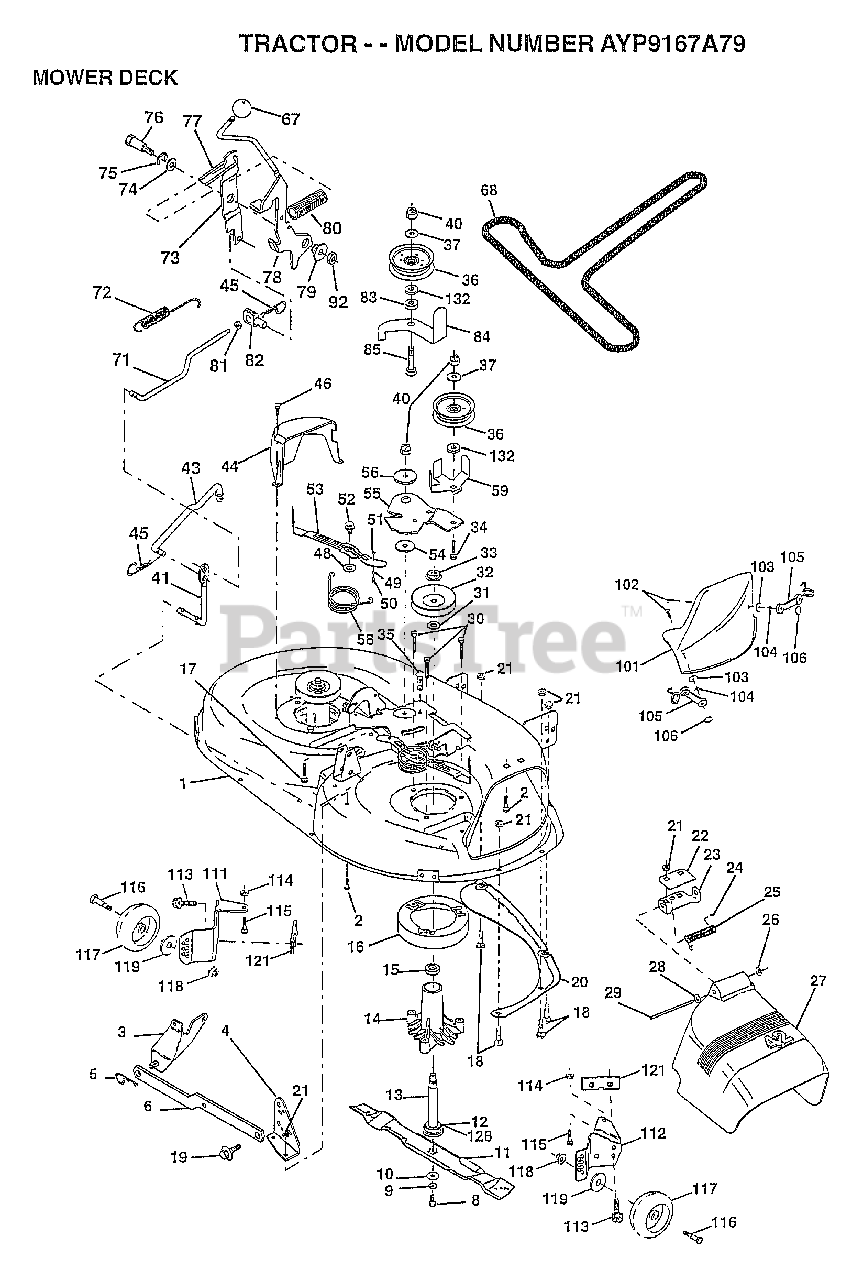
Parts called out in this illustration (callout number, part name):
1	DECK.WELD.42.
2	BOLT
3	BRKT ASM SWAY BAR
4	BRKT DECK SW BAR
8	BLADE BOLT
10	WASHER.HARD.BLADE
11	"BLADE.42"" MULCHER"
12	BEARING.BALL
14	HSG ASM MANDREL
15	BEARING
16	STRIPPER RND MWR
17	BOLT RDHD 3/8-16
18	BOLT
19	BOLT SHD 5/16-18
22	STIFFENER BRKT
23	DEFLECTOR BRKT
24	CAP-SLEEVE LT
25	SPRING TORSION
26	NUT PUSH M
27	DEFLECTOR.SHIELD
28	WASHER
29	HINGE ROD
31	WASHER
32	PULLEY.MANDREL.42
34	BOLT
35	XMAS TREE FASTNER
36	FLAT IDLER PULLEY
37	WASHER
41	PIVOT ROD
43	ROD CLUTCH W/NIBS
44	GUARD MAND LH BLK
45	RETAINER M
46	SCREW.1/4-20X5/8
48	HARD SMALL WASHER
49	ROLLER ASM-CAM
50	SHOULDER BOLT
51	LOCKNUT
52	BOLT.SHLD.5/16-18
54	HARDENED WASHER
55	ARM-IDLER
56	SPACER RETAINER
58	SPRING TORSN BRAK
59	GUARD IDLER TUV
67	KNOB T(3/8 HOLE)
68	BELT.V.T-PATH
71	ROD CLUTCH 38/42
72	RETURN SPRING
73	CLUTCH ARM SECOND
74	WASHER
75	RING
76	SHOULDER BOLT
77	SPRING KEEPER
78	LEVER ASM-CLUTCH
79	BUSHING
80	SPRING.CLUTCH.MWR
81	TRUNION ADJ
82	NUT
83	WASHER
84	"KEEPER-BELT,FIXED"
85	BOLT RDHD 3/8-16
92	NUT
101	"COVER.MULCH.42"""
102	SCREW
103	WASHER #10
104	LOCKWASHER
106	WELDNUT
111	BRACKET.GWHL.LH.
112	BRACKET.GWHL.RH.
113	SCREW
116	BOLT.SHOULDER
117	WHEEL GAGE DONUT
118	LOCKNUT
119	WASHER
121	BRACKET.EXTRD.GWL
128	WASHER.FELT.
132	WASHER GT
